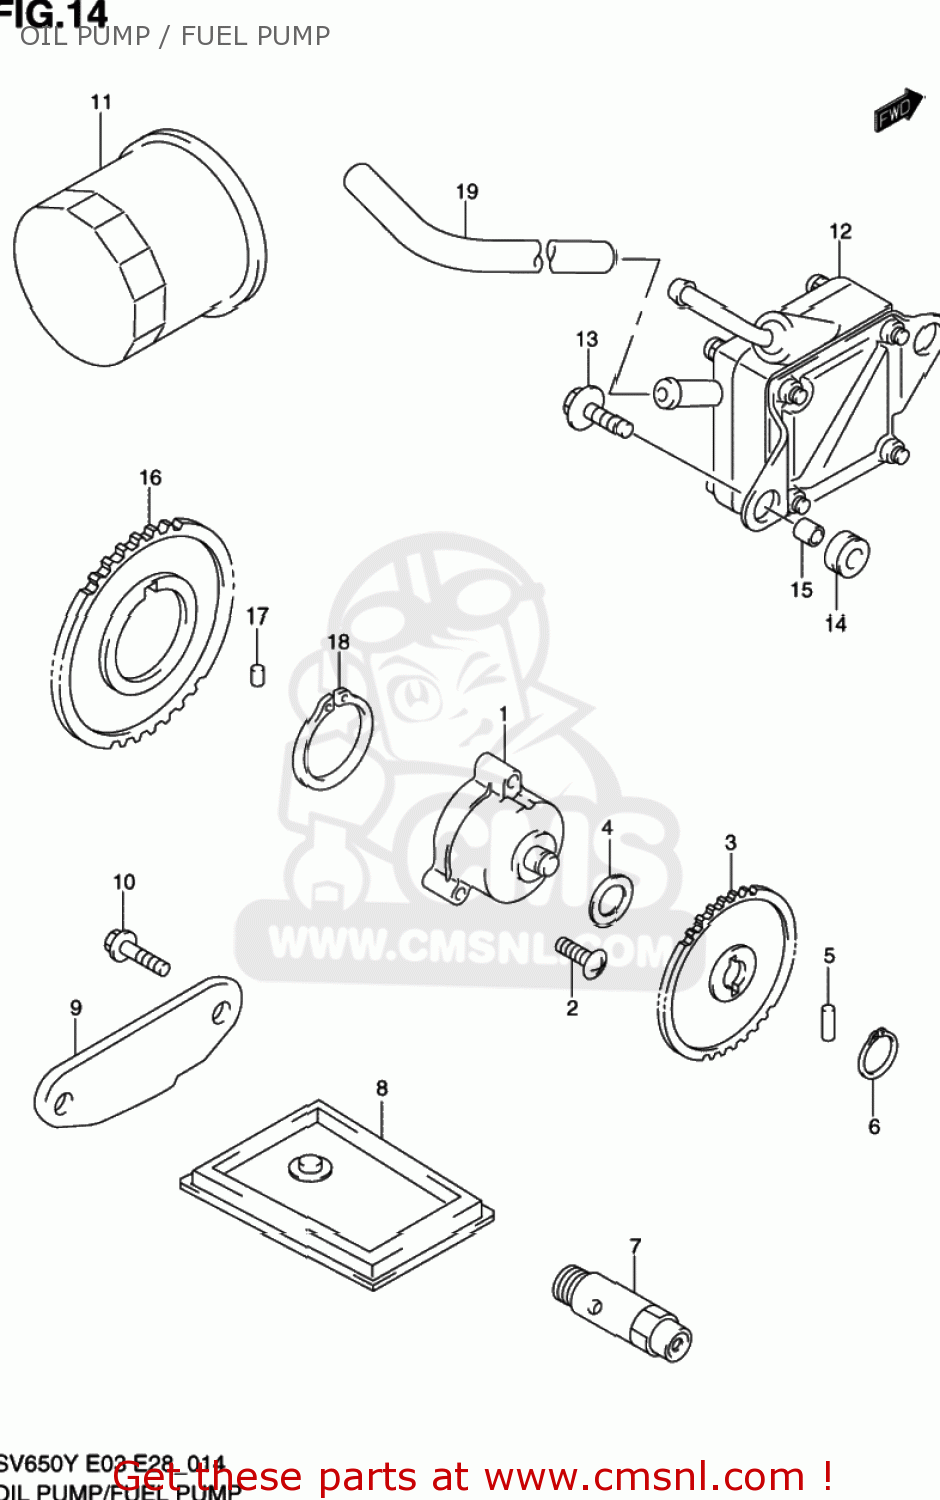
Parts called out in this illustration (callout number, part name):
1	PUMP ASSY,ENGINE OIL
2	SCREW
3	GEAR,ENG OIL PUMP DRIVEN
4	SHIM(10X18X0.5)
5	PIN(4X18.5)
6	CIRCLIP,10MM
7	VALVE ASSY,OIL RELIEF
8	STRAINER,ENGINE OIL
9	CAP,OIL STRAINER
10	BOLT
11	FILTER ASSEMBLY,ENGINE OIL
12	PUMP ASSY,FUEL
13	BOLT(6X20)
14	CUSHION
15	SPACER(6.5X9X6.5)
16	GEAR,ENG OIL PUMP DRIVE
17	PIN(6X6)
18	CIRCLIP
19	HOSE(5X10X600)
